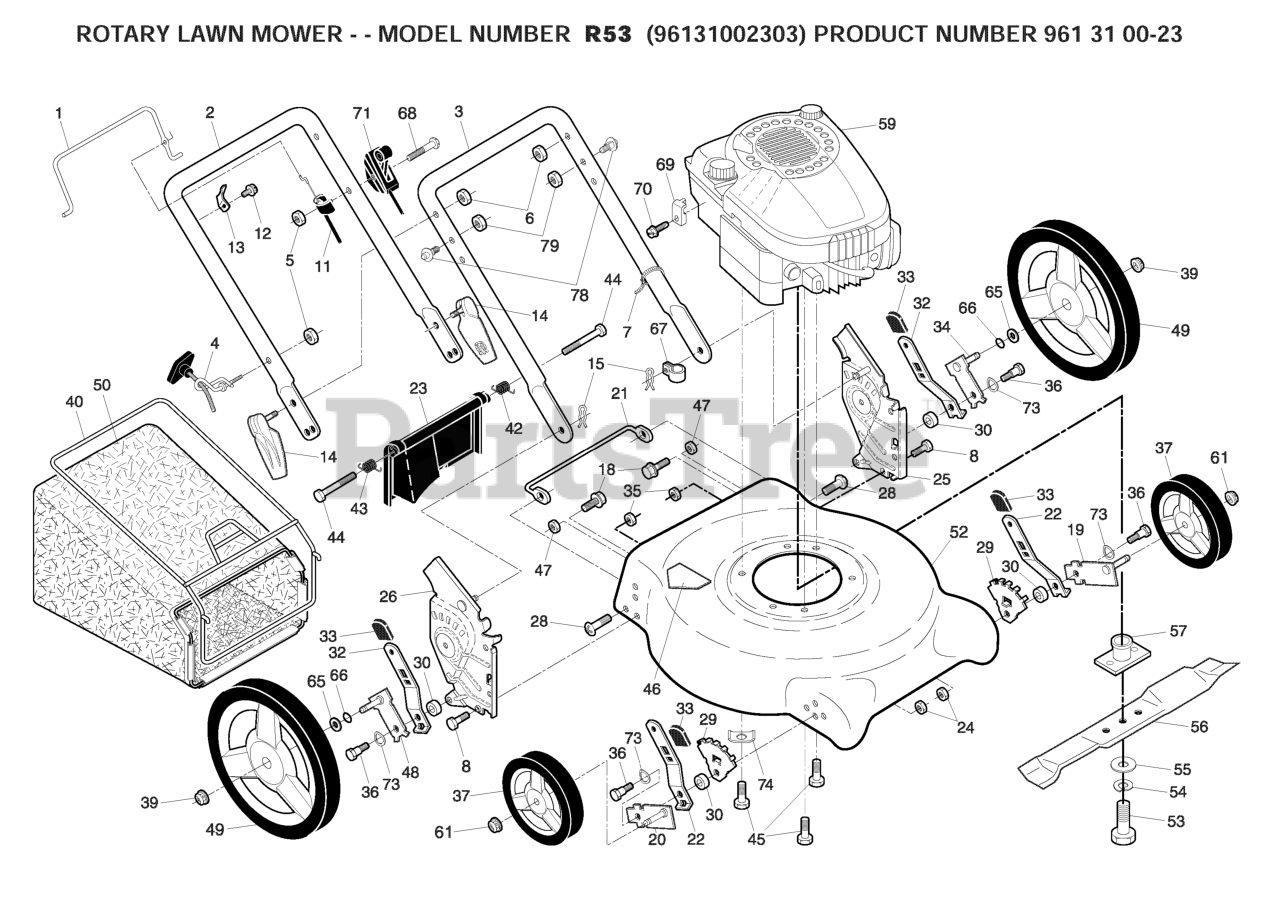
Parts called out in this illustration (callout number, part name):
1	BAIL.MZR.STD.ORANGE
3	HANDLE.LOWER.ECON.PNT
4	RB GUIDE.ROPE.STD.BLK.ZIN WSL
5	NUT
7	TIE GUIDE
8	BOLT.FIN.HEX.5/16-18X3/4
11	CABLE.MZR.B&S.45.LT.PUSH
13	BRACKET
14	ASM.QUICK.RELEASE
15	HAIRPIN COTTER
18	SCREW 1/4X20
19	AXLE ARM ASSY FRONT LH
20	AXLE ARM ASSY FRONT RH
22	SELECTOR SPRING, FRONT
23	REAR DOOR ASSY
24	LOCKNUT 5/16-18
25	RP BRKT.ASM.HAND.HW.21.LT.ORNG
26	RP BRKT.ASM.HAND.HW.21RT.ORNG
29	WHEEL ADJ BRACKET FRONT
30	SPACER.HEIGHT.ADJUSTER
32	SPRING.SEL.EXT.21.DOMED.12/14
34	AXLE ARM ASSY REAR LH
35	LOCKNUT 5/16-18
36	SHOULDER BOLT 5/16-18
37	WHEEL AND TIRE ASSY, REAR
39	NUT.HEX.FLANGE.3/8-16.LOCKNUT
40	FRAME.BAG.21.REAR.DOMED.PUSH
42	SPRING.LH.22.REAR.DOOR.EZ.EMPT
43	SPRING.RH.22.REAR.DOOR.EZ.
45	BOLT 3/8-16X1-1/8
46	DECAL.INTERNATIONL.CUTFINGER
48	AXLE ARM ASSY REAR RH
49	RP.WHEEL.12X1.75H 3 SPOKE.RAD
53	SCREW, HEX HD 3/8-24 X 1-3/8
54	LOCKWASHER
55	WASHER,HARDEN
56	BLADE.21.PUSH
57	ADAPTER.BLADE
61	NUT.HEX.FLANGE.3/8-16.LO(3 2)
65	WASHER.FLAT.1/2
66	O-RING..070X.487.NEOPRENE
67	CLIP.CABLE.BLK
69	CABLE CLAMP(ENGINE)
70	SCREW.HEX.HEAD.WASHER.10-16
72	NUT
73	WASHER.CURVED.CYLINDRICAL
74	WASHER.ENGINE.BZP
78	STUD.QUICK.ADJUST
79	NUT.LOCK.5/16-18
